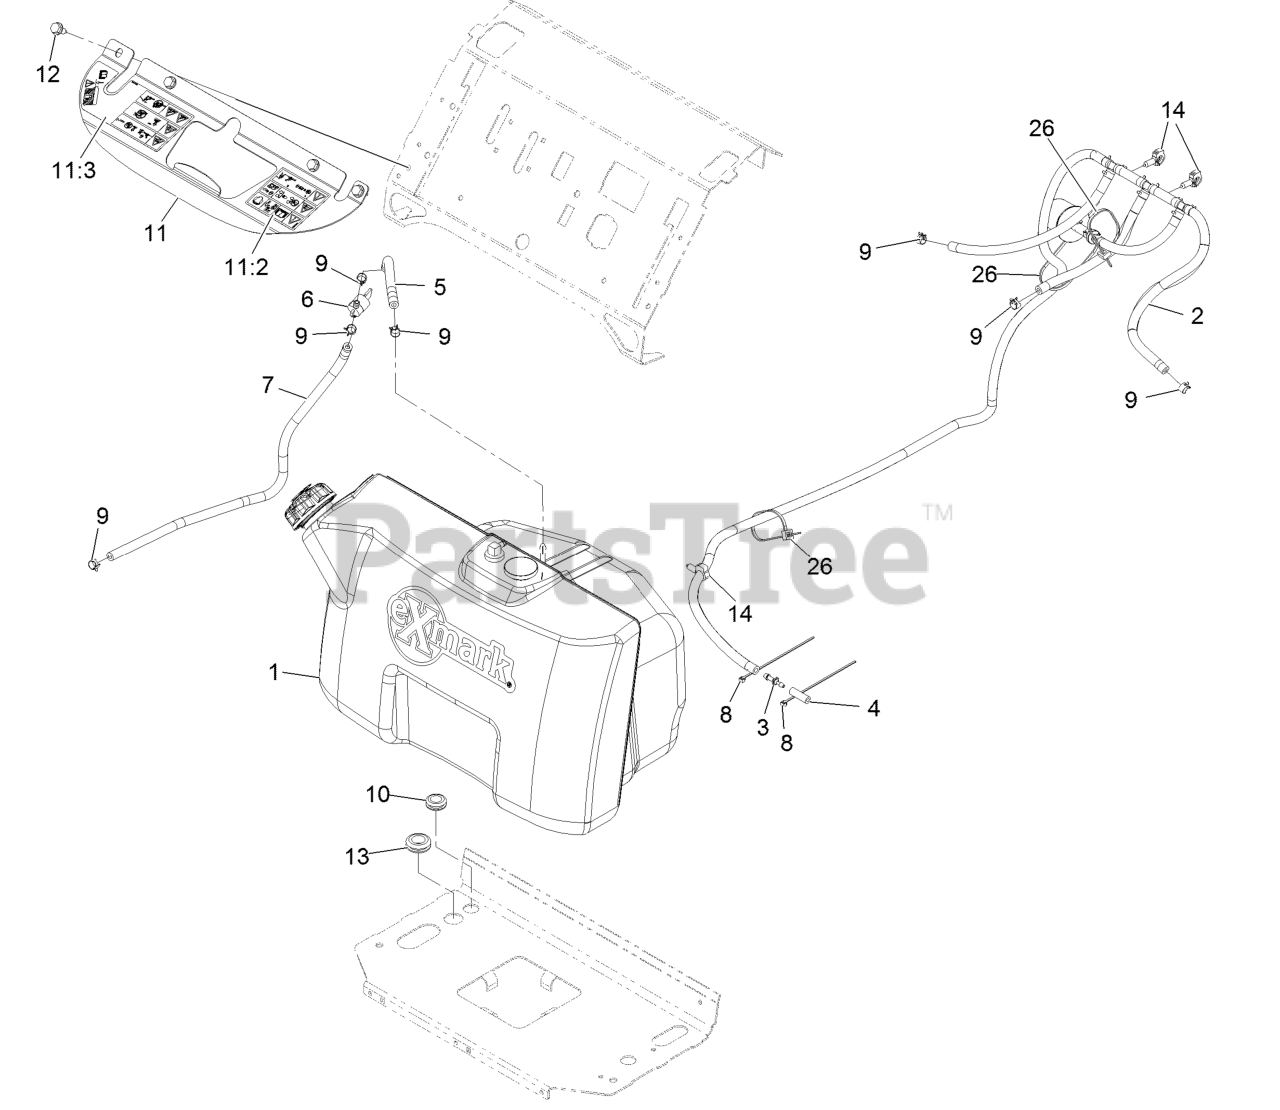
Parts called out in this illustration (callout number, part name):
2	VENT ASM
3	FITTING-STRAIGHT
4	HOSE-FUEL
5	HOSE-FUEL
6	VALVE-FUEL
7	HOSE-FUEL
8	TIE-CABLE
9	CLAMP-HOSE
10	GROMMET
11	BRACKET-TANK
11:2	DECAL-WARNING LH
11:3	DECAL-WARNING RH
12	Screw-HWH 5/16-18 X 3/4 Tf
13	GROMMET
14	CLIP-HARNESS
26	TIE-CABLE
